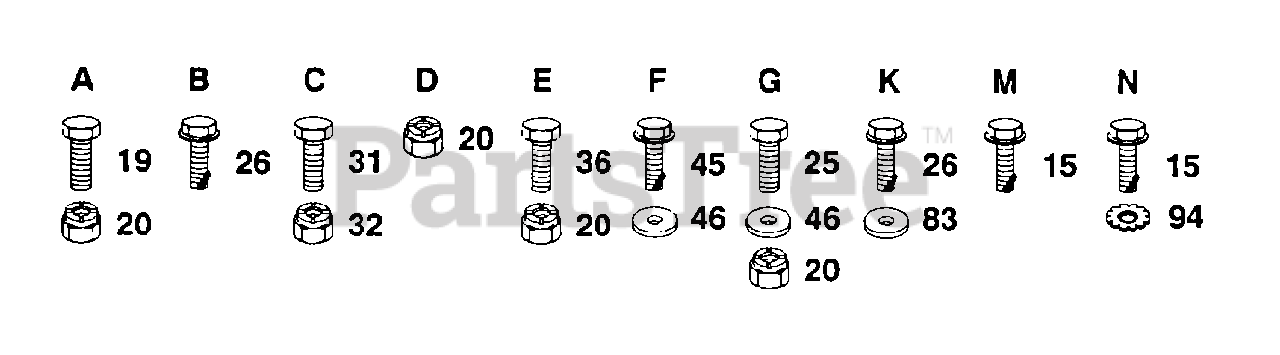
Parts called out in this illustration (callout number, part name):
15	SCREW
19	BOLT
25	BOLT
26	SCREW
31	BOLT
45	SCREW
46	WASHER
83	WASHER
94	LOCKWASHER
